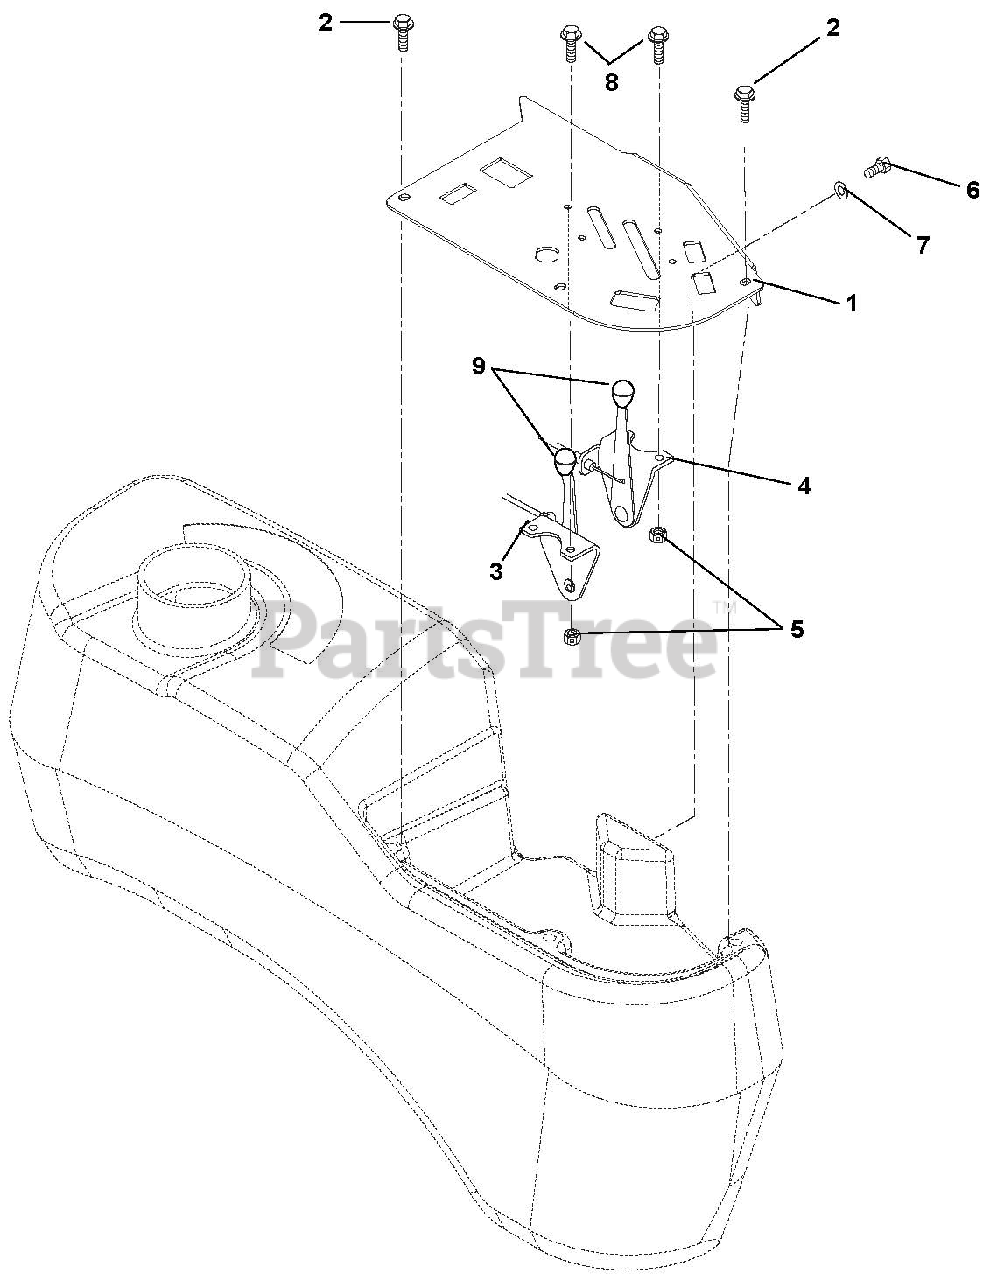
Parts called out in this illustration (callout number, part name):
1	Panel, Control
2	Screw, Machine Hex Washer Head 10-24 x .38 Stainless
3	Throttle, Control
4	Choke Control
5	Nut, Locking Nyloc 10-24 With Insert
6	Bolt, Hex .31-18 x .75 Grade 5
7	Washer, Flat Steel .38 x .875 x .083
8	Screw, Machine Hex Washer Head 10-24 x .50
9	Knob, Control Black .38-16 x .62
